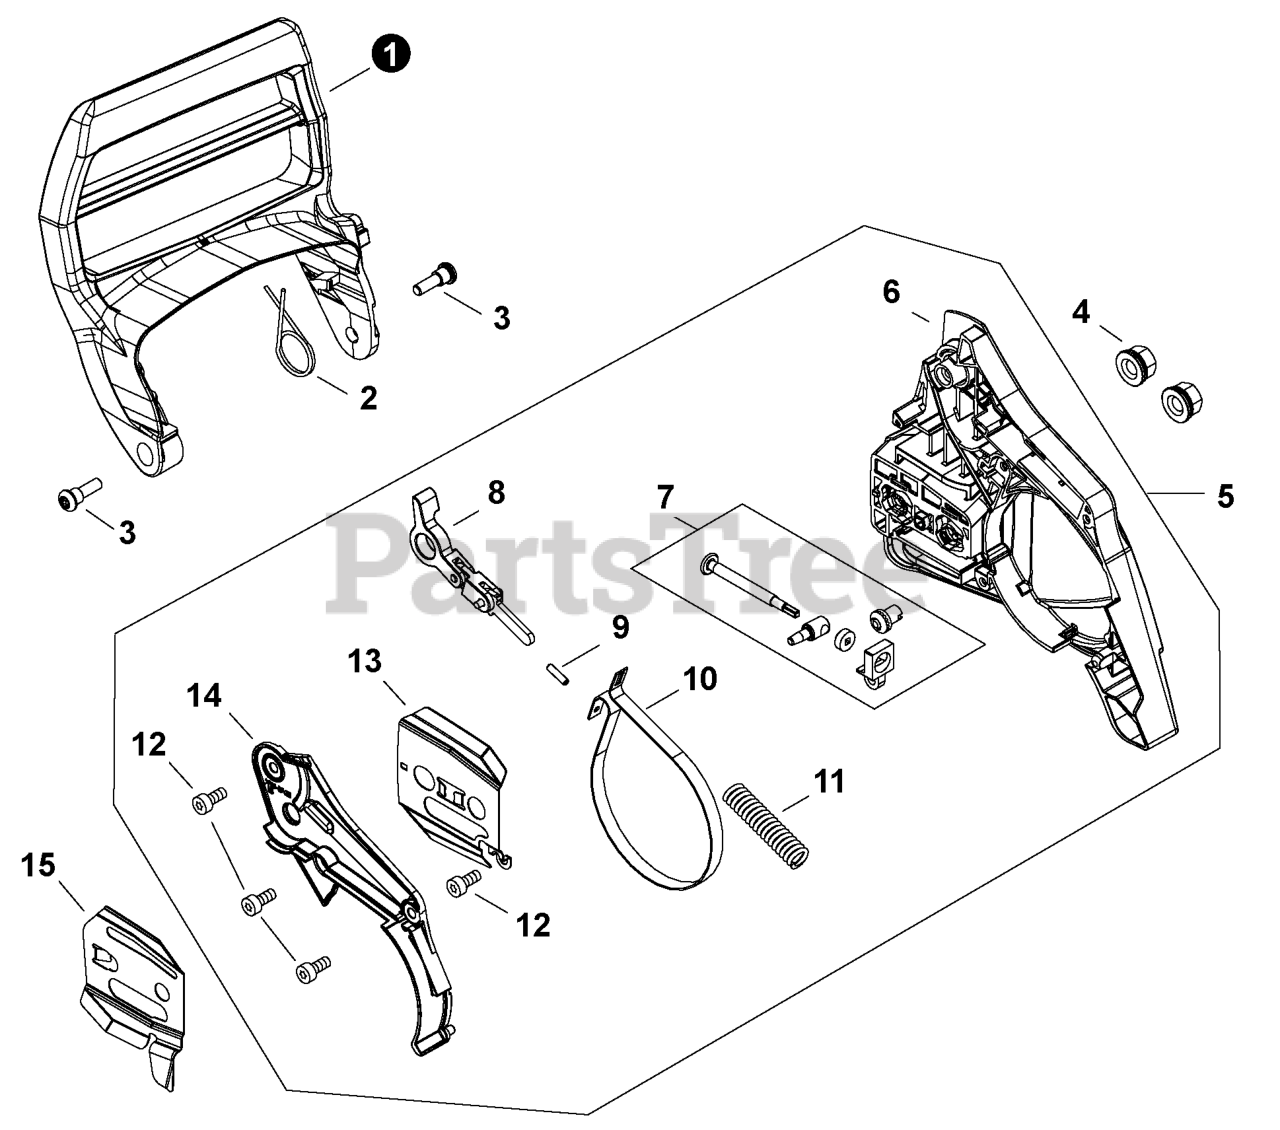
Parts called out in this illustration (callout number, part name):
1	LEVER, BRAKE
2	SPRING, TORSION
3	BOLT, TORX 5x13
4	NUT, FLANGE M8x1.25
5	SPROCKET GUARD ASSY
6	GUARD, SPROCKET
7	TENSIONER KIT, CHAIN
8	CONNECTOR, BRAKE
9	PIN 3x12
10	BAND, BRAKE
11	SPRING, COMPRESSION
12	BOLT, TORX 4x12
13	PLATE, GUIDE - OUTER
14	COVER, BRAKE
15	PLATE, GUIDE - INNER
